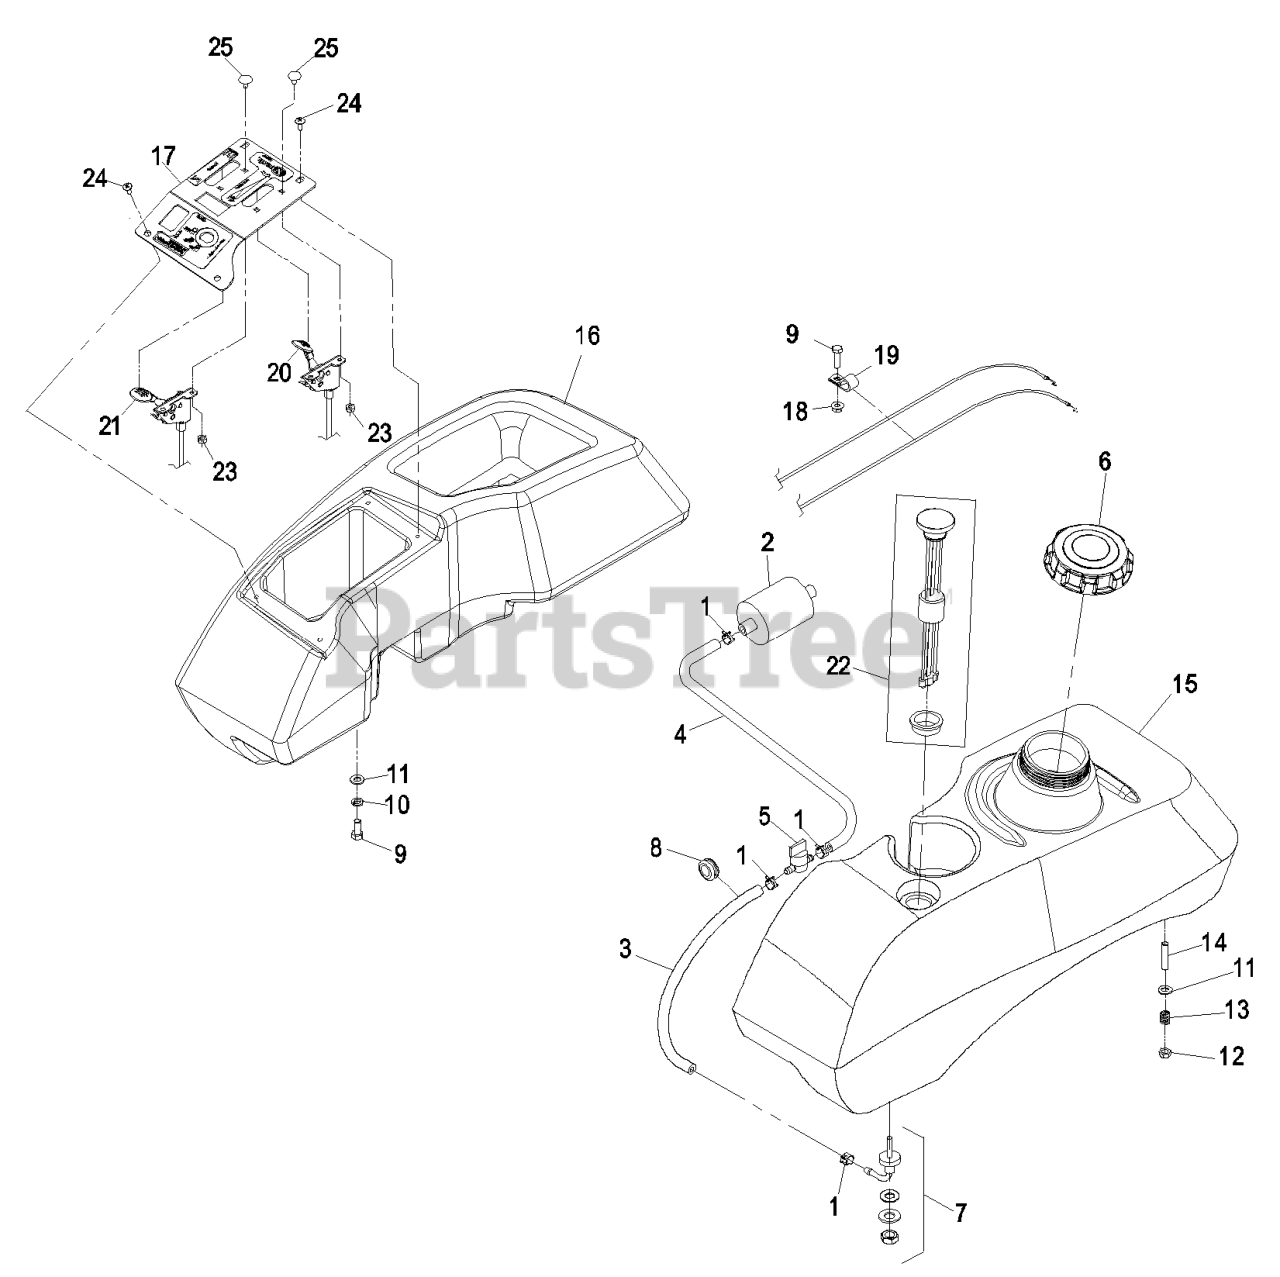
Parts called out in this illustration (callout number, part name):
2	Briggs & Stratton Part No. 493629 Fuel Filter
3	HOSE-FUEL
4	HOSE-FUEL
5	VALVE-FUEL
6	CAP-FUEL, GAS
7	FITTING-FUEL, BULKHEAD
8	GROMMET
9	SCREW-HH
10	WASHER-LOCK
11	WASHER-PLAIN
12	NUT-LOCK, NI
13	SPRING-TANK, FUEL
14	STUD
15	KIT,FUEL TANK LH LCT
16	ASM, TANK RH LCT S.O.
17	PANEL,CONTROL W/DECALS
19	CLIP-LOOM
20	CONTROL,THROTTLE
21	CONTROL,CHOKE
23	NUT-LOCK, NI
24	SCREW-PPH
25	BOLT-CARR
